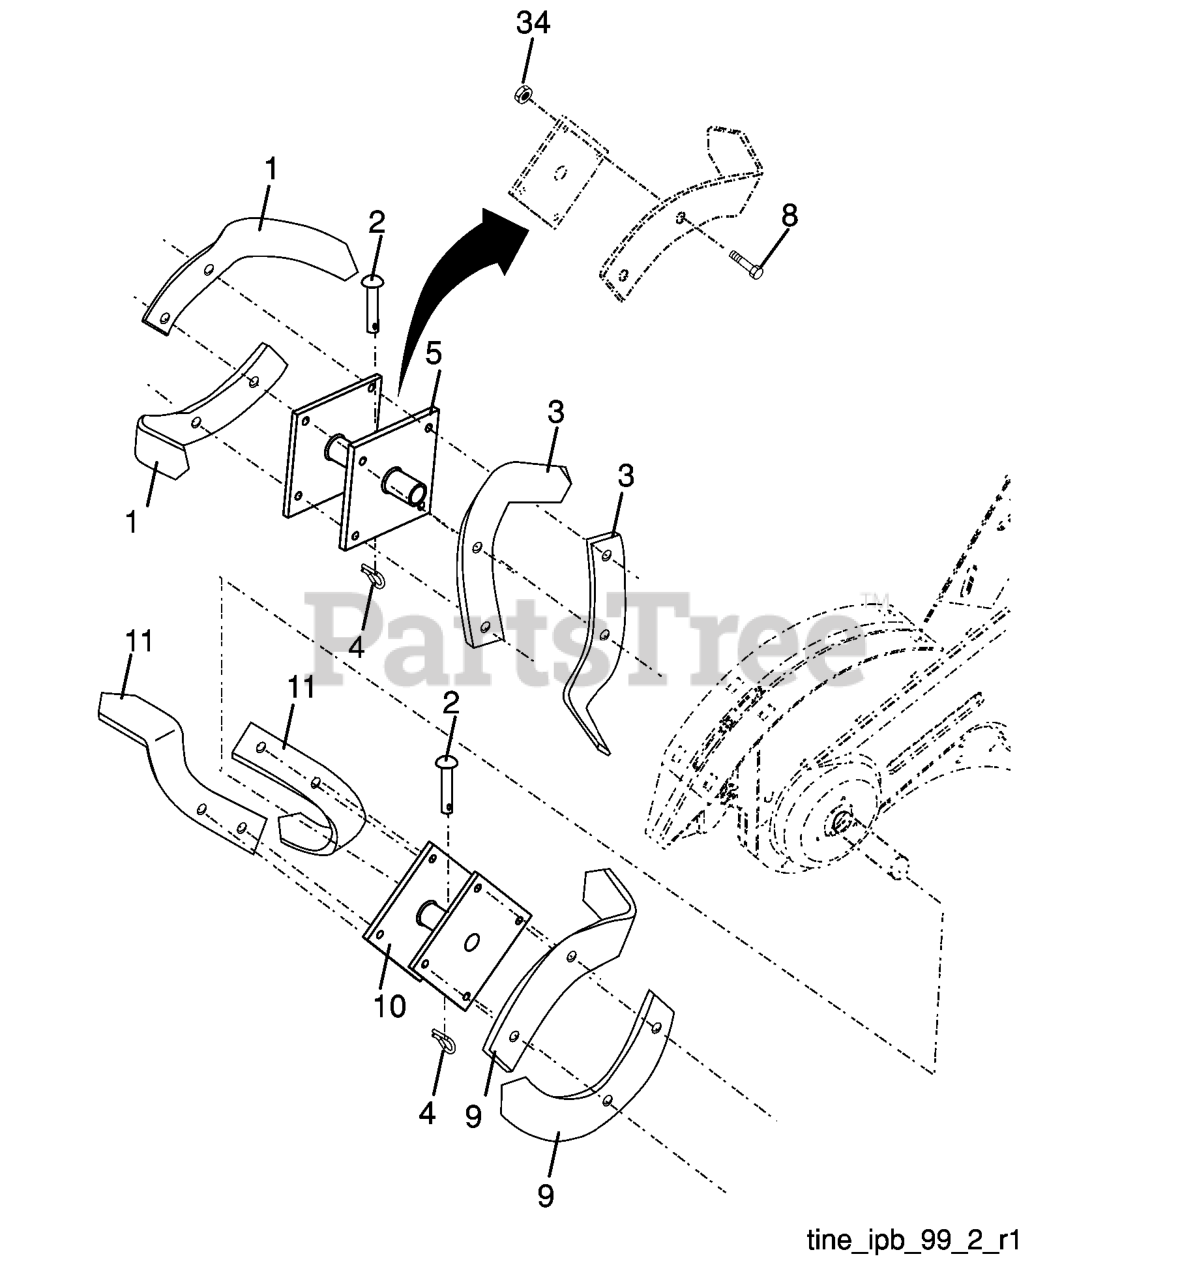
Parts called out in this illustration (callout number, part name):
1	TINE TI
2	PIN RETAINING SCREW
3	TINE.LH.12"(72L)
4	SPRING RETAINER
5	HUB.&.PLATE.LH.TILLER.BLACK
8	BOLT.HEX.001X20.37-24X1.ZINC
9	TINE TI
10	HUB.ASM.RH.14".BLACK.TILLER
11	TINE.RH.12"(72R)
34	NUT CROWNLOCK 3/8-24
